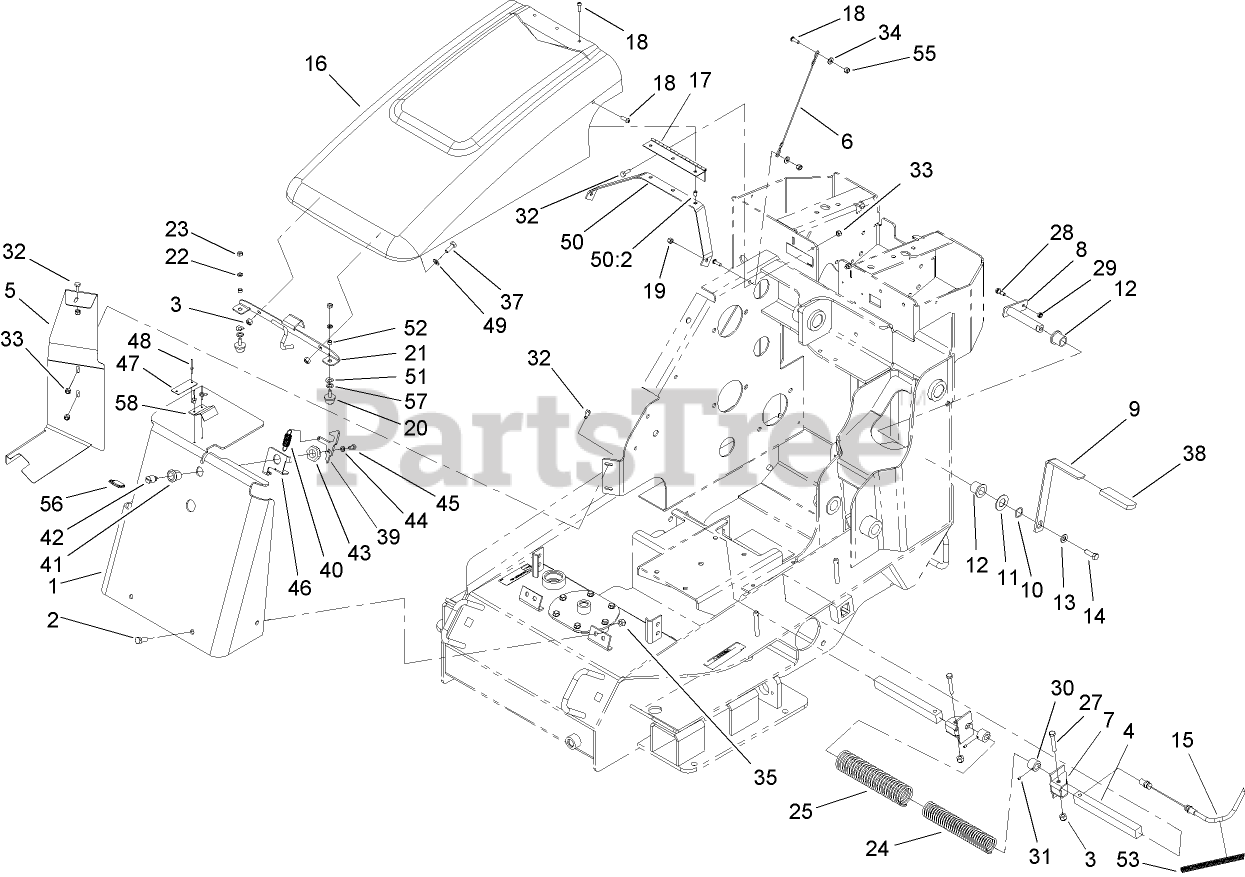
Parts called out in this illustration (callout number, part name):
2	SCREW-HH
3	NUT-LOCK, NI
4	BAR-BRAKE
5	DEFLECTOR-EXHAUST
6	LANYARD
7	BRACKET-CABLE
8	BRAKE SHAFT ASM
9	HANDLE-BRAKE
10	Washer-Wave
11	WASHER-FLAT
12	BUSHING
13	WASHER-FLAT
14	SCREW-HH
15	CABLE-BRAKE
16	HOOD ASM
17	HINGE-HOOD
18	SCREW-PRH
19	NUT-LOCK, NI
20	BUMPER
21	ROD LATCH ASM
22	WASHER-LOCK
23	NUT-HEX
24	SPRING-BRAKE
25	SPRING-BRAKE
27	SCREW-HH
28	BOLT-SHOULDER
29	NUT-LOCK, NI
30	Tube-Guide
31	SCREW-HSH
32	SCREW-HH
33	NUT-LOCK, NI
34	WASHER-FLAT
35	NUT-LOCK, NI
37	SCREW-HH
38	GRIP-HANDLE
39	CAM-LATCH
40	SPRING
41	HOUSING-LATCH
42	INSERT-LATCH
43	NUT-LOCK, NI
44	WASHER-LOCK
45	SCREW-HH
46	BRACKET-LATCH
47	PLATE-HOT SURFACE
48	RIVET-POP
49	WASHER-PLAIN
50	SUPPORT-HOOD
50:2	INSERT-THREADED
51	WASHER-SPRING
52	SPACER
53	TUBE-CONVOLUTED
55	NUT-LOCK, NI
56	KEY-LATCH, HOOD
57	WASHER-FLAT
58	RAMP-LATCH
